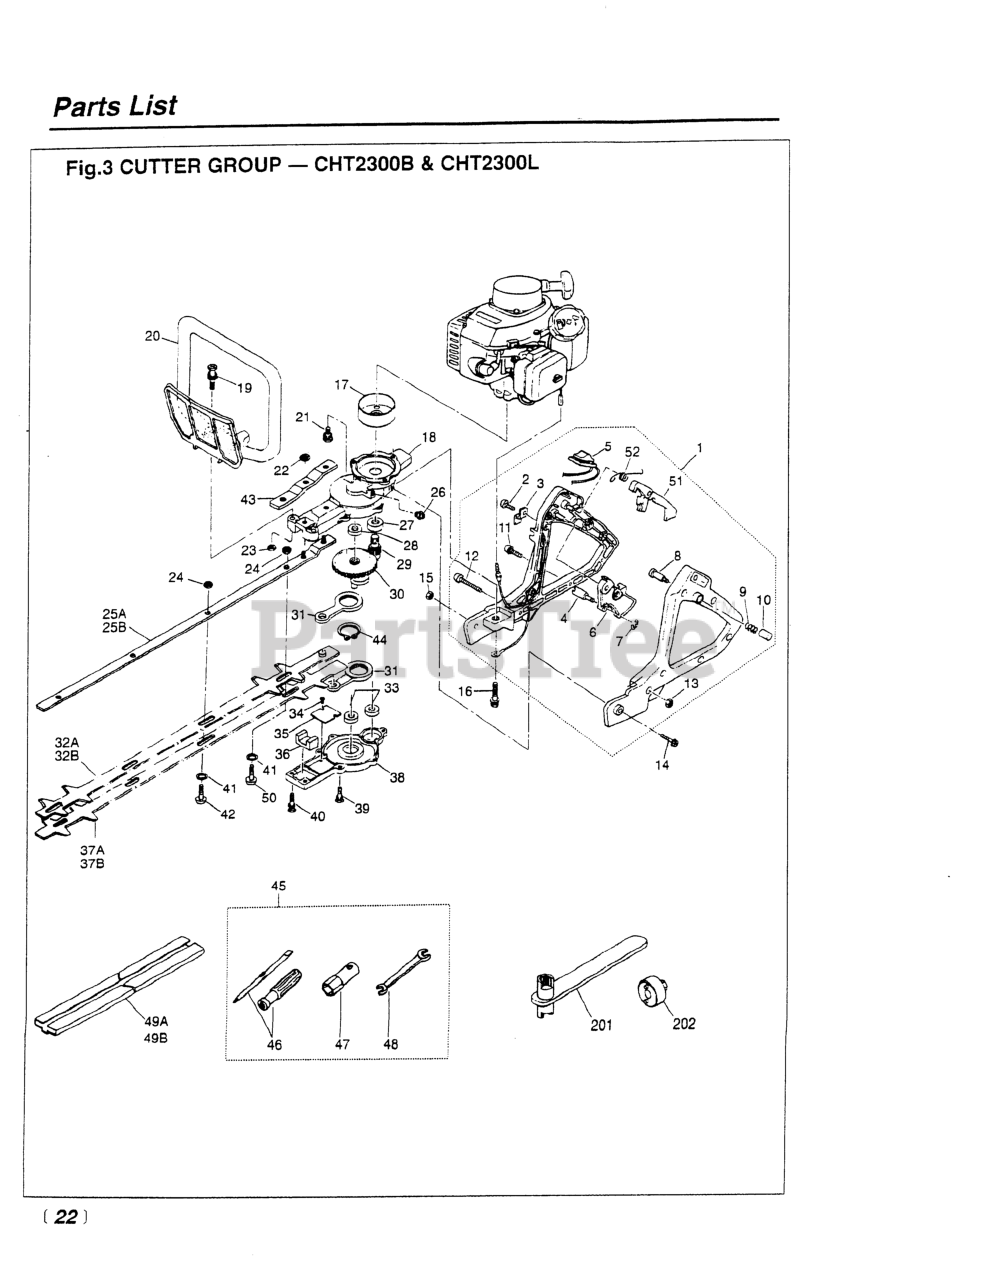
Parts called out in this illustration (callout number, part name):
1	HANDLE, REAR ASSY (RPL 3873-)
2	SCREW, M4 x 10
3	PLATE
4	END, CABLE
5	SWITCH
6	LEVER, THROTTLE (RPLS -13220)
7	RING, SNAP
9	SPRING
10	CAP, PIN
11	SCREW, M4 X 16
12	SCREW, M4 x 30
13	NUT, M6 X 4
14	BOLT, M6 X 50
15	NUT, M6 X 5
16	BOLT, M6 X 40
17	DRUM, CLUTCH
18	CASE, MIDDLE (RPLS -11110)
19	BOLT, M6x35 (RPLS -50635)
20	HANDLE (RPLS -12101)
21	BOLT, M6 X 14
22	NUT
23	NUT, M6 X 5
24	NUT, M6
25A	BAR, GUIDE, 24
26	FITTING, GREASE
27	BEARING
28	BEARING
29	PINION
30	GEAR COMPLETE
31	ROD
32A	BLADE, UPPER DOUBLE, 24
33	BEARING
34	SCREW, M3 x 5
35	PLATE
36	FELT
37A	BLADE, LOWER DOUBLE, 24
38	CASE, LOWER
39	BOLT, M5 x 16
40	BOLT, M5 X 20
43	PLATE (RPLS 3880-11130)
44	RING, SNAP, M25 X 1.2
45	TOOL SET
46	SCREWDRIVER
47	SOCKET, HEX, 3/4
48	SPANNER, 8 X 10 (RPLS 2540- )
49A	COVER, BLADE (24
52	SPRING (REPLACES -13321)
202	WRENCH (TOOL)
